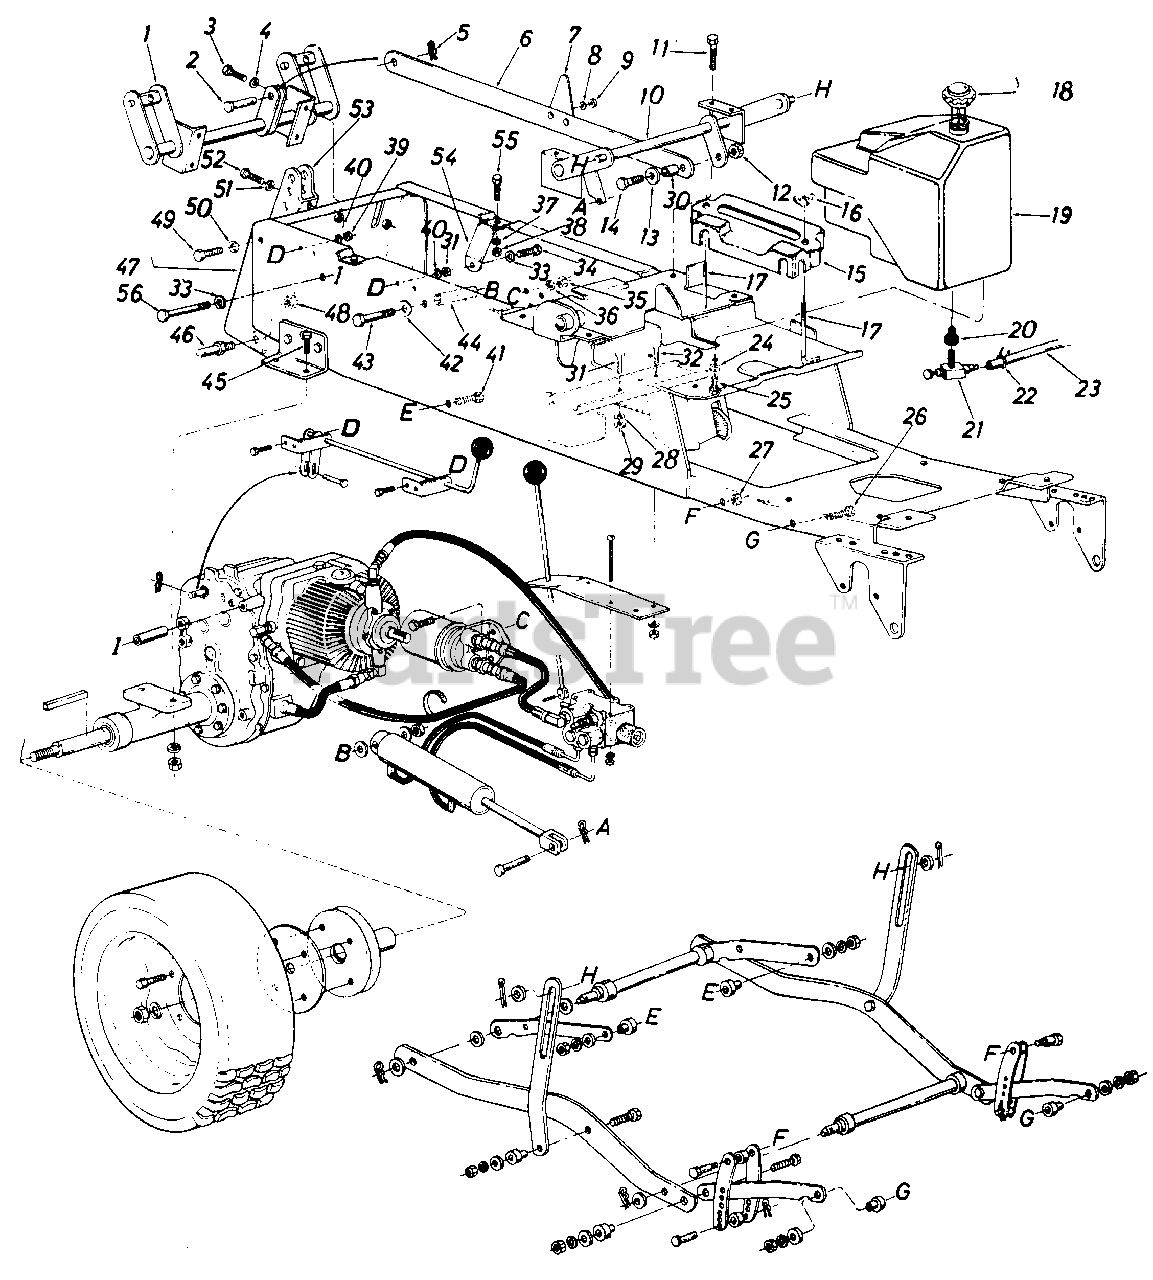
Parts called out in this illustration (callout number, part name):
3	Hex Scr. 3/8-16 x 1.00" Lg. Grade 5
4	L-Wash. 3/8" Scr. H.D.
5	Cotter Pin 1/8" Dia. x 1.25" Lg.
8	L-Wash. 5/16 Scr.
9	Hex Nut 5/16-18 Thd.
12	Hex Cent. L-Nut 1/2-20 Thd.
14	Hex Scr. 1/2-20 x 1.25" Lg.
15	Battery Cover
16	Wing Nut 1/4-20 Thd.
17	Battery Hold Down Rods
18	Gas Tank Cap
19	Gas Tank Ass'y.
20	Bushing
21	Fuel Shut-Off Valve with Screen
22	Gas Line Clamp 7/16"
23	Gas Line 30" Lg.
25	Hex Scr. 1/4-20 x .38" Lg.
26	Hex Scr. 3/8-24 x 1.50" Lg.*
27	Hex Nut 3/8-16 Thd.
28	L-Wash. 3/8" Scr.
29	Hex Nut 3/8-16 Thd.
30	Push Bar Sleeve
31	Hex Scr. 3/8-16 x 1.00 Lg. Grade 5
32	Hex Scr. 5/16-18 x .75" Lg.
33	L-Wash. 1/2" Scr.
34	Hex Scr. 1/2-13 x 1.25" Lg.
35	Hex Nut 5/16-18 Thd.
36	L-Wash. 5/16" Scr.
37	L-Wash 3/8" Scr. H.D.
38	Hex Nut 3/8-16 Thd.
39	Hex Nut 1/4-20 Thd.
40	L-Wash. 1/4" Scr.
41	Hex Scr. 3/8-24 x 1.50" Lg.
42	Fl-Wash. .50" I.D. x 1.25 O.D.
43	Hex Scr. 1/2-20 x 3-1/2" Lg. Grade 5
44	Spacer for Cyl i nder
45	Hex Scr. 3/8-16 x 1.75" Lg.
46	Link Clevis Pin
49	Hex Scr. 3/8-16 x .75" Lg. Grade 5
50	L-Wash. 3/8" Scr.
51	L-Wash. 3/8" Scr. H.D.
52	Hex Scr. 3/8-16 x .75" Lg. Grade 5
54	Transmission Brace
55	Hex Scr. 3/8-16 x 1.00" Lg.
56	Hex Scr. 1/2-13 x 2.75" Lg.
